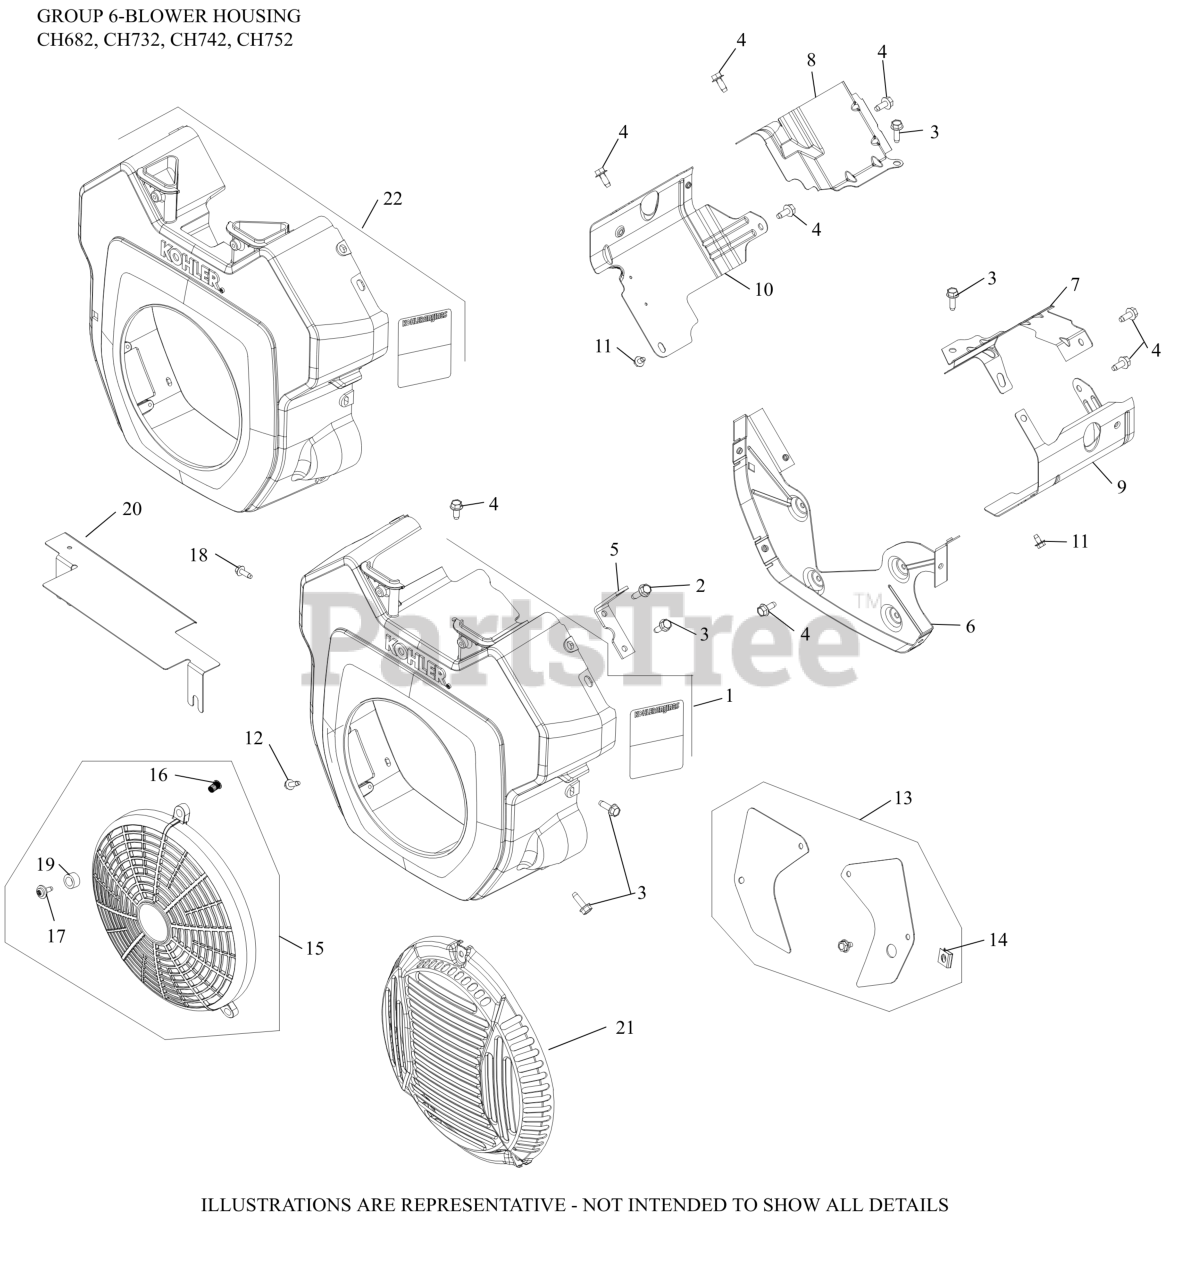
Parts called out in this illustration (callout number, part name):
1	HOUSING, BLOWER
2	SCREW, THREAD FORMING
3	SCREW, THREAD FORMING
4	SCREW, THREAD FORMING
5	STRAP, LIFT
6	KIT, BACKING PLATE
7	BAFFLE, VALLEY #1 CYLINDER
8	BAFFLE, VALLEY #2 CYLINDER
9	KIT, CYL BAFFEL #1 SIDE
10	BAFFLE, LEFT BARREL
11	SCREW, THREAD FORMING
12	SCREW, THREAD FORMING
13	KIT, ACCESS PANEL
14	CLIP, BAFFLE MOUNTING
15	KIT, FIXED GUARD
16	INSERT, THREADED (M5)
17	SCREW, SEMS
18	SCREW, THREAD FORMING
